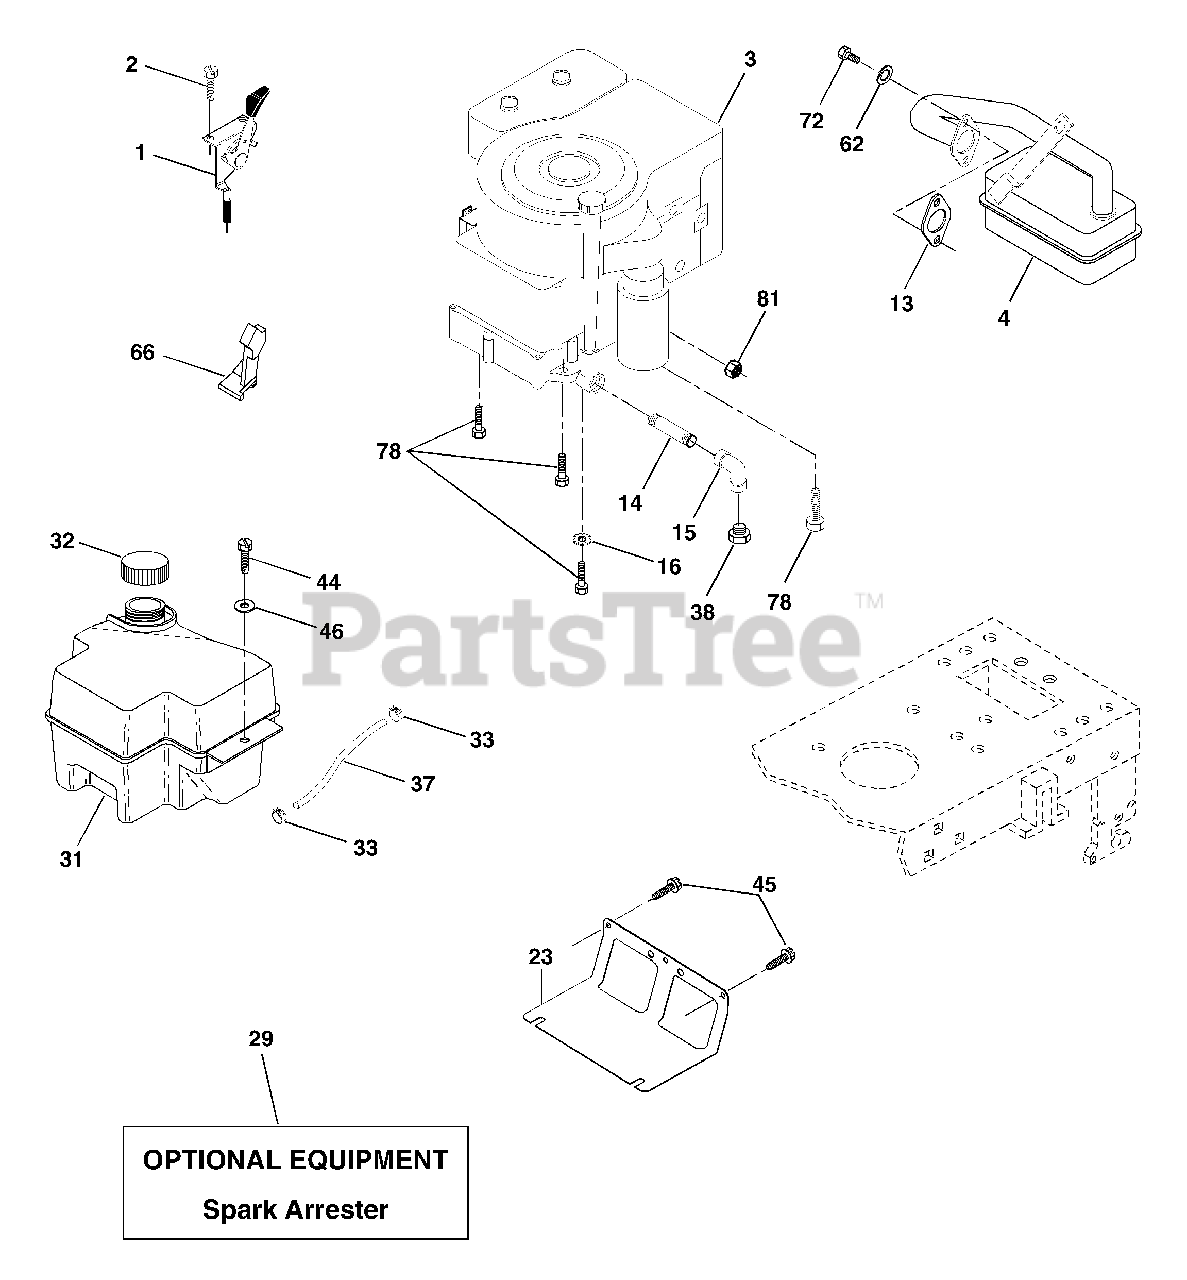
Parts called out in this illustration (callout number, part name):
1	Control Throt /Ch Lh
2	Screw Hex Thd Cut 1/4-20x5/8 T
4	Muffler Exhaust B&S Lt
13	Gasket 1 313 Id Tin Plated
14	Nipple Pipe 3/8 Npt X 3"
15	Elbow Std 90 Degree 3/8-18 Npt
16	Washer Lock Ext Tooth 3/8
23	Shield Browning/Debris Guard
29	Arrestor Spark
31	Tank Fuel 2.00 Fr
32	Cap Asm Fule Top Vent N/Lany
33	Clamp Hose Blk
37	Line Fuel 20"
38	Plug Oil Drain
44	Screw Hexwsh Thdrol 1/4-20 x 3/4
45	Screw 3/8-16 x 3/4
46	Washer 9/32 X 7/8 X 16ga
62	Washer Lock Hvy Hlcl Spr 5/16
66	Stop Throttle 3000 Rpm
72	Screw Hexhd Cap 5/16-18 x 5/8
78	Screw 3/8-16x1-1/4
81	Nut Flange 1/4-20 Starter Nut
